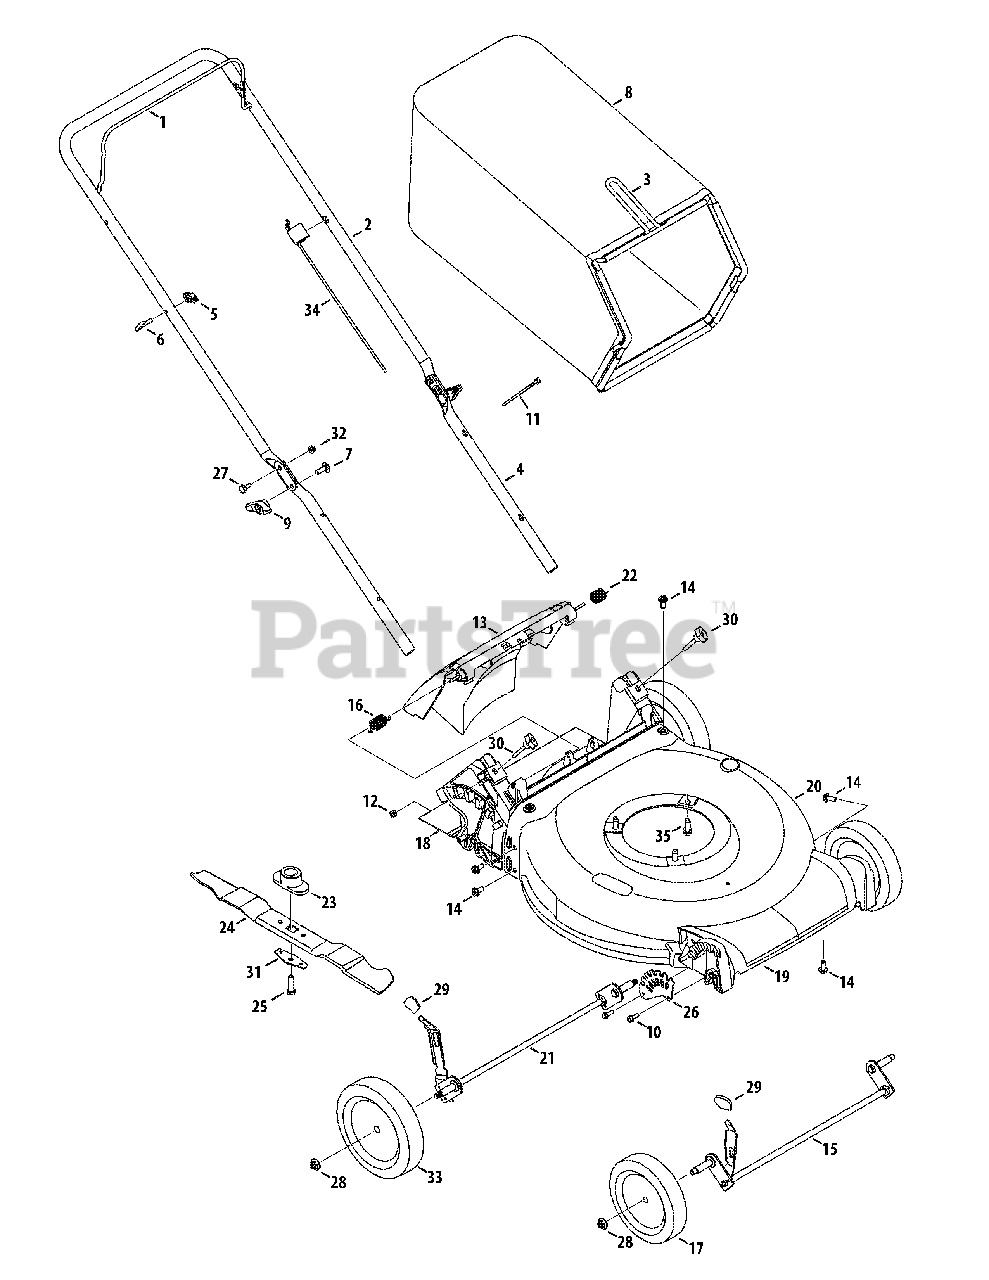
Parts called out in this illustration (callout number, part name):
1	Blade Control
2	Upper Handle
3	Grass Catcher Frame
4	Lower Handle
5	Wing Nut
6	Rope Guide
7	Carriage Screw ,5/16-18
8	Grass Bag
9	Wing Knob
10	Screw, 1/4-15 x .750
11	Cable Tie
12	Nut, Sq., 1/4-20
13	Rear Discharge Door Assembly
14	Screw, 5/16-14 x .750
15	Front Axle Assembly
16	Torsion Spring - RH
17	Front Wheel
18	Rear Baffle
19	Front Cover
20	Deck - 21"
21	Rear Axle Assembly
22	Torsion Spring - LH
23	Blade Adapter
24	Mulching Blade
25	Screw , 3/8-24 x 1.50
26	Front Height Adjuster Plate
27	Sldr. Screw, .375 x .126 x 1/4-20
28	Flange Lock Nut, 3/8-16
29	Adjustment Lever Knob
30	Wing Nut
31	Blade Bell Support
32	Nut, Flange Lock, 1/4-20
33	Rear Wheel
34	Control Cable
35	TT Sems Screw, 3/8-16 x 1.0
36	Trail Shield
